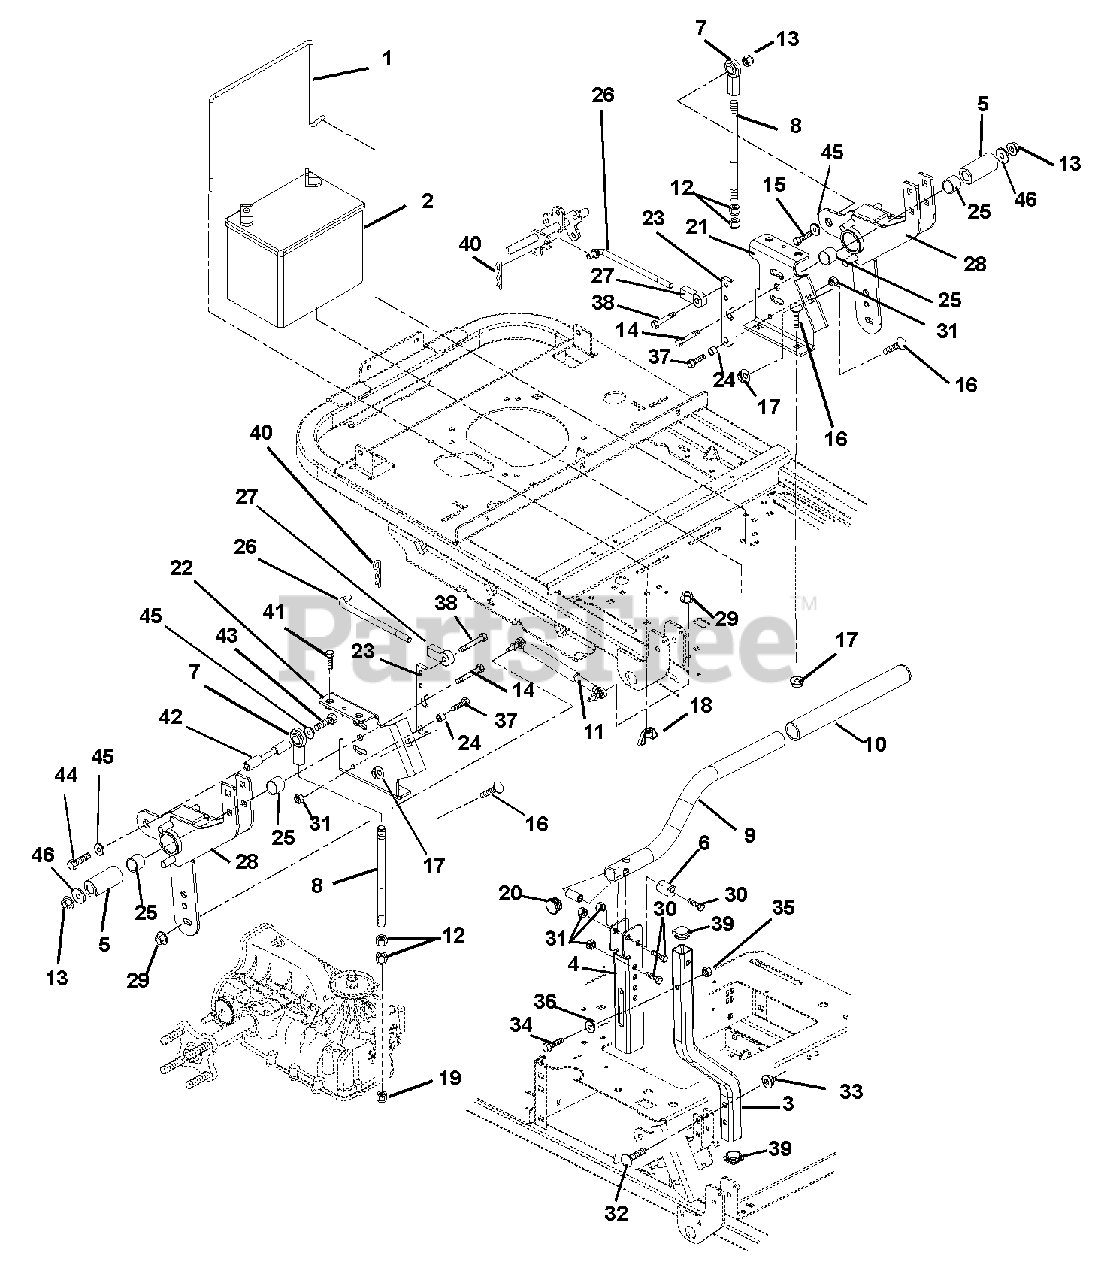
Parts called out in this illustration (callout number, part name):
1	BATTERY ROD
2	BATTERY, 300 CCA 10U1L
3	CONTROL ARM
4	CHANNEL, HANDLEBAR ADJUSTMENT
5	BSHG, SPCR .502X.997X2.03 PM
6	BSHG,ECCEN .328X.750X1.01 PM
7	ROD END, 1/2 RH
8	ROD-TRANSAXLE LH
9	HANDLEBAR
10	GRIP - HANDLEBAR
12	NUT-JAM .50-20 GR2 YWZC
13	@NUT-LK-TOP-FLG .50-13 YWZC
14	@BLT-HEX .50-13X3.00 GR5 YWZC
15	@BLT-HEX .50-13X1.75 GR5 YWZC
16	@BLT-RDHDSQNK .38-16X1.00 G5YZ
17	@NUT-LK-NYL-FLG .38-16 YWZC
18	NUT-LK WING .250-20 YWZC
19	NUT-LK-JAM-NYL .50-20 GR2 YWZC
20	CAPLUG, HANDLEBAR
21	WMT, CONTROL LH
22	WMT, CONTROL RH
23	BRACKET, NEUTRAL STOP
24	BSHG, SPCR .330X.500X.385
25	BRG, 1.00 X 1.12 X .75
26	LINK, BRAKE ROD
27	ROD END, .38 RH
28	WMT, STEERING CONTROL
29	NUT, TOP LOCK FLG 8X1.25 YWZC
30	@BLT-HEX .31-18X1.75 GR5 YWZC
31	@NUT-LK-NYL-FLG .31-18 YWZC
32	@BLT-RDHDSQNK .31-18X1.75 G5YZ
33	@NUT-LK-TOP-FLG .31-18 YWZC
34	@BLT-HEX .25-20X1.75 GR5 YWZC
35	@NUT-LK-NYL .250-20 YWZC
36	BSHG-FLG .265X.437X.250X.750
37	@BLT-HEX .31-18X1.25 GR5 YWZC
38	@BLT-HEX .38-16X.75 GR5 YWZC
39	CAPLUG SQR 1-14-20
40	PIN-HAIR INT .08X.18X1.18 YWZC
41	SCR-CAP .38-16X2 HSHD PRECT 30
42	LINKAGE, STEERING
43	@BLT-HEX .50-13X1.25 GR5 YWZC
44	@BLT-HEX .50-13X1.00 GR5 YWZC
45	WSHR-LK .500X.151 HVY YWZC
46	WSHR-FL-STL.511X1.441X.125 YWZ
